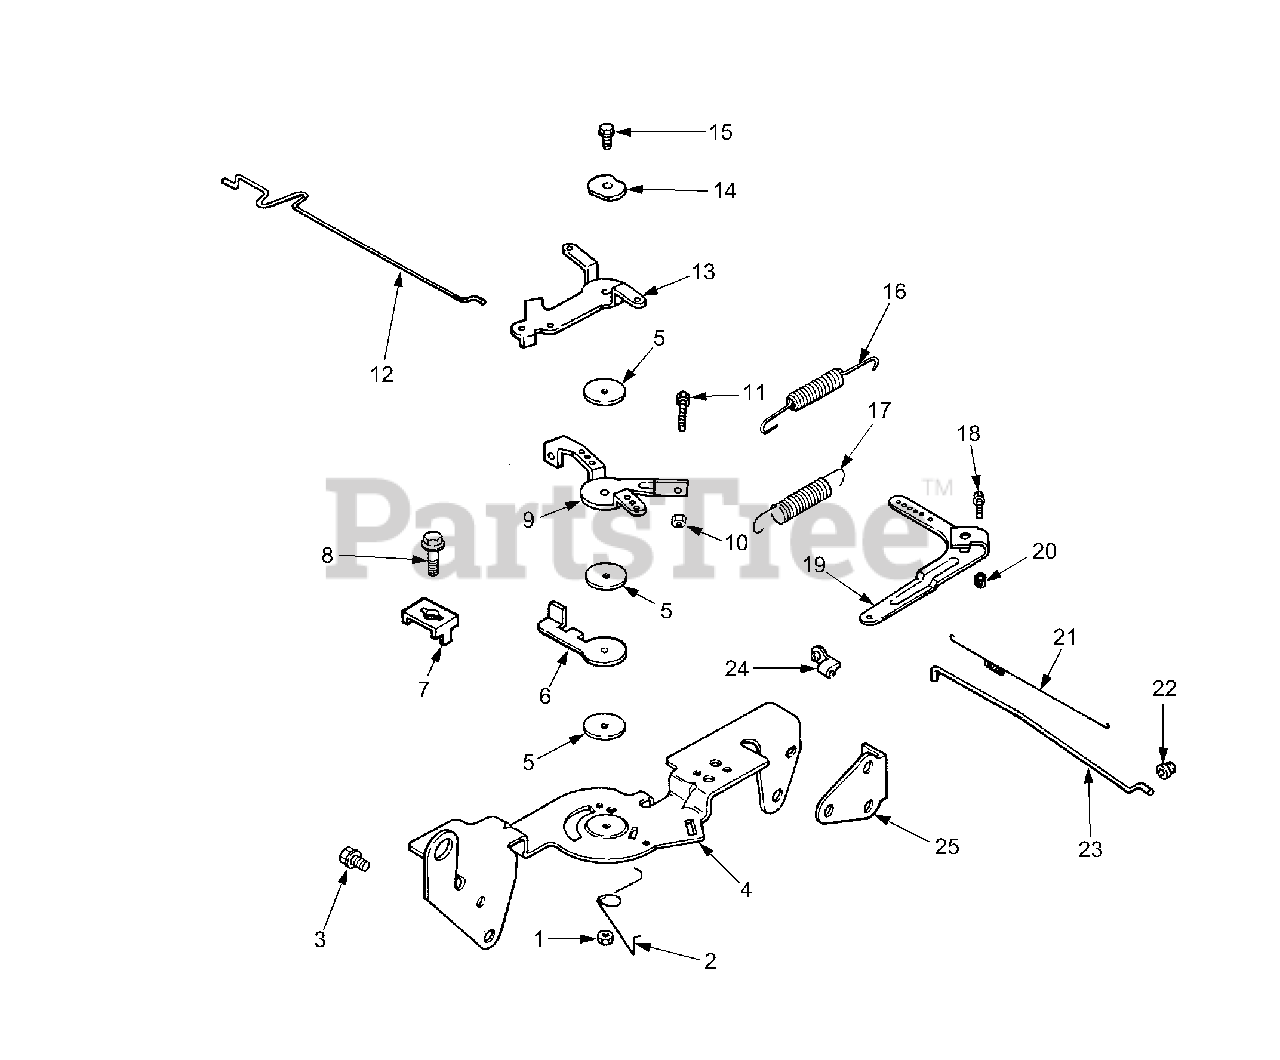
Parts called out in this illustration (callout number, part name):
1	Nut, Hex Lock M5 x 0.8
2	Spring, Choke Return
3	Screw, Hex Flange M6 x 1.0 x 16
4	Bracket, Control
5	Washer, Plain 5.5 mm
6	Lever, Throttle Actuator
7	Clamp,Cable,
8	Screw, Hex Flange M5 x 0.8 x 16
9	Lever, Throttle Control
10	Nut, Hex M4 x 0.7
11	Screw, Hex Cap M4 x 0.7 x 30
12	Linkage,Choke
13	Lever, Choke
14	Washer, Spring 1/4"
15	Screw, Hex Flange M5 x 0.8 x 20
16	Spring, Throttle Limiter
17	Spring, Governor
18	Screw, Carriage
19	Lever, Governor
20	Nut, Hex Flange M6 x 1.0"
21	Spring, Linkage
22	Bushing, Linkage Retaining
23	Linkage, Throttle
24	Bushing, Linkage Retaining
25	Bracket Support
